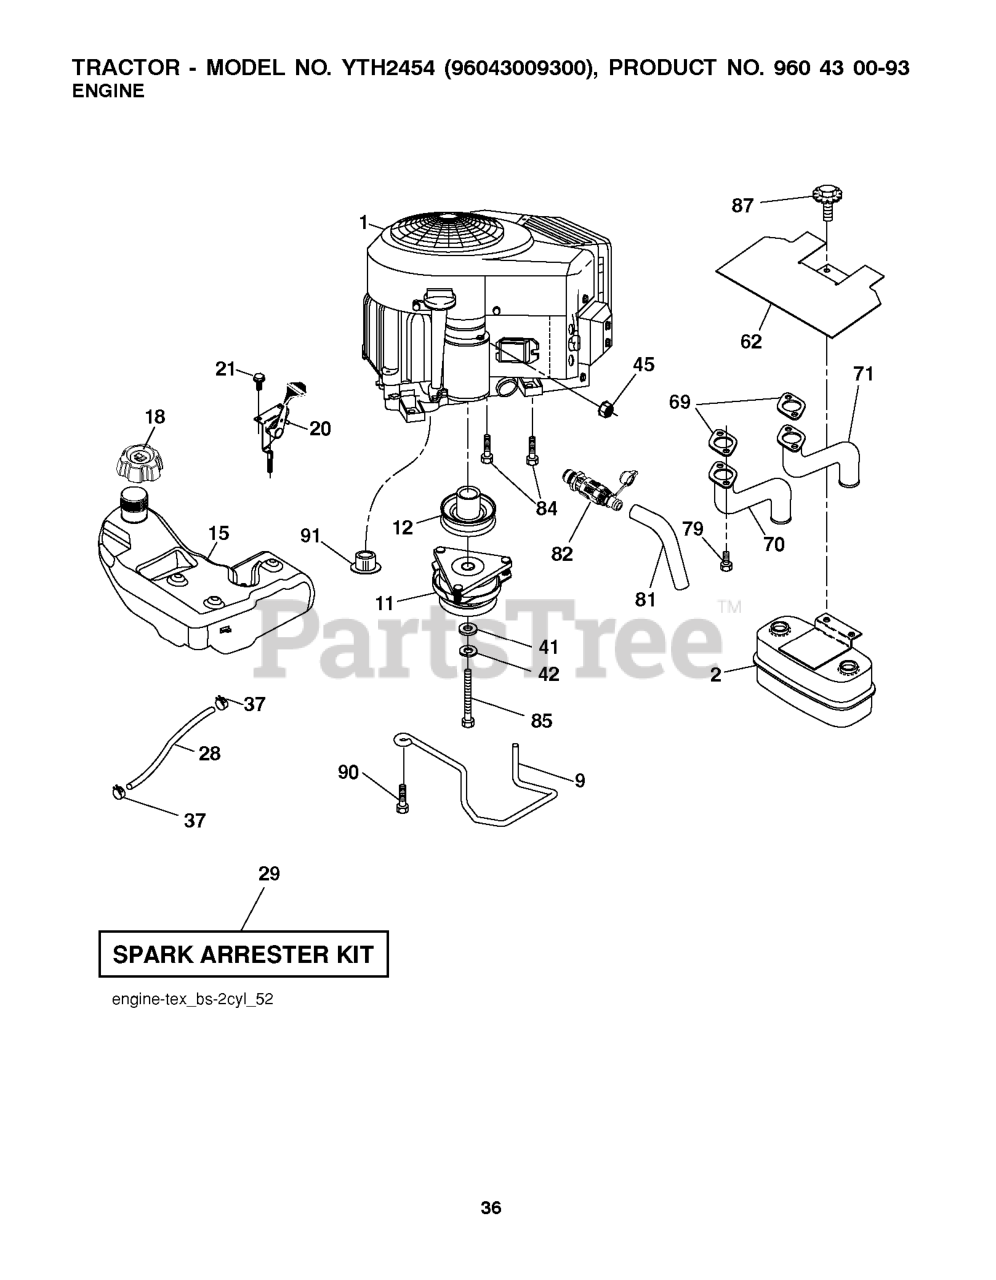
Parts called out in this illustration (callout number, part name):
2	MUFFLER.TWIN.CYL.LOW.TONE
9	KEEPER.BELT.ENGINE.4.2
11	CLUTCH.ELECTRIC.LT.48"*
12	PULLEY.ENGINE.TUFFTORQ
15	TANK.FUEL.SIDE-FILL.3.NON-EPA
18	RP CAP FUEL
20	CONTROL.TH/CK.COBRA.B&S.TWN.BK
21	SCREW.#10 X 0.750.BOS
28	LINE.FUEL.64"REAR.EMIS
29	KIT.SPARK ARRESTOR 794945 B&S
37	HOSE CLAMP
42	LOCKWASHER
45	NUT
62	RP SHIELD HEAT MUFFLER
69	GASKET.MUFFLER
70	RP.EXHAUST.TUBE.LH.BS/TWIN
71	EXHAUST.TUBE.RH.BS/TWIN
79	SCREW.SOCKET.HEAD.5/16-18
81	TUBE, DRAIN OIL ASM.
82	VALUE.OIL.DRAIN
84	SCREW.3/8-16
85	BOLT HEX 7/16-20X4-1/4"
87	BOLT.5/16-18UNCX3/4 W/SEMS.BLK
90	SCREW 3/8-16X1
91	BUSHING.1.375OD
